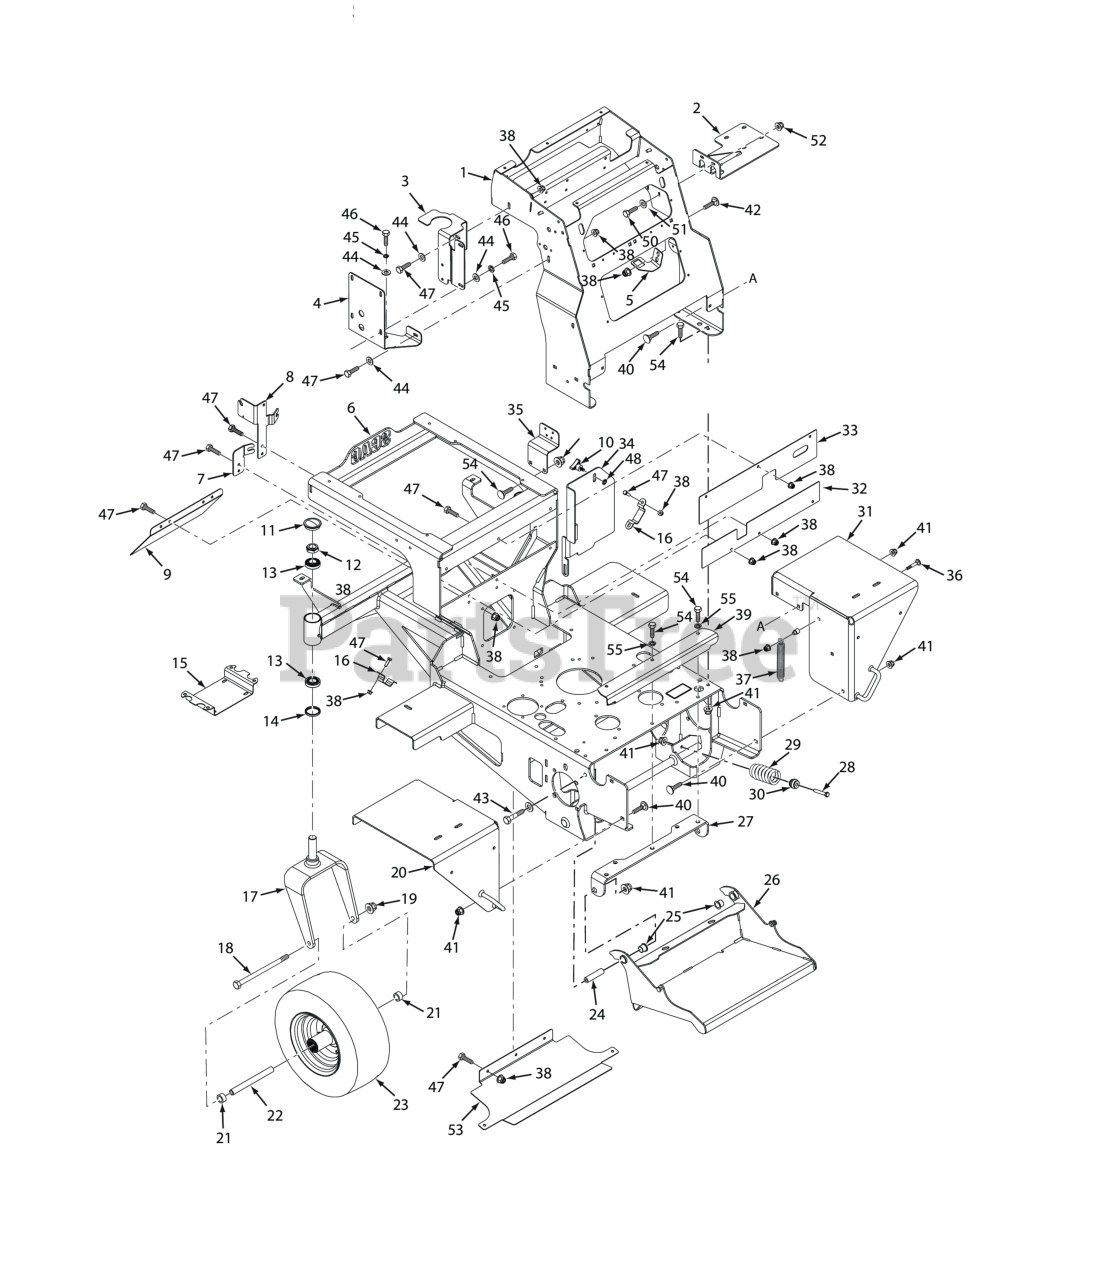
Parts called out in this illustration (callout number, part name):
1	Handlebar Weldment
2	Mounting Bracket, Hose Reel
3	Mounting Bracket, Oil Reservoir
4	Mounting Bracket, Fuel Tank
5	Mounting Bracket, Brake Switch
6	Mainframe Weldment, STS
7	Mounting Bracket, Door Cable
8	Mounting Bracket, Cable
9	Cover, Vent
10	Knob, w/ Stud, 5/16 - 18
11	Cap, Grease
12	Nut, Hex Elastic Stop 1.0"-14
13	Bearing Cone
14	Upright Post Weldment, RH
15	Mounting Bracket, Foamer Accessory (optional)
16	Bracket, Hose
17	Caster Yoke Weldment
18	Bolt, Hex Head 1/2-13 x 9-1/2" (61V & 72A/VS)
19	Nut, Elastic Stop 1/2-13, (STT-52 & STTII-52)
20	Fender, LH
21	Spacer, Caster Wheel
22	Sleeve, Caster Wheel (61V, 72A/VS)
23	Caster Wheel Assembly, 16 x 6.50 - 8
24	Spacer
25	Bearing, .750 I.D. Plastic
26	Footplate Assembly (Incl. #25)
27	Footplate Weldment
28	Bolt, Hex Head 3/8-16 x 2-1/4" - Stainless Steel
29	Spring, Suspension Platform
30	Mount, Spring
31	Fender, RH
32	Guard, Rear Hopper Lower
33	Guard, Rear Hopper Uppler
34	Battery Door
35	Mounting Bracket, Strainer
36	Bolt, Carriage 5/16-18 x 1.75 - Stainless Steel
37	Spring,Counter Balance
38	Locknut, 5/16-18 Flg. Elastic Stop - Stainless Steel
39	Mounting Bracket, Operator Presence
40	Bolt, Carriage 3/8-16 x 1.0 - Stainless Steel
41	Nut, Flange Elastic Stop 3/8 - 16 - Stainless Steel
42	Bolt, Carriage 5/16 - 18 x 1" - - Stainless Steel
43	Bolt, Hex 3/8 - 16 x 4.00 - Stainless Steel
44	Washer, Flat 5/16 -.375 x .875 x .0547/.104 - Stainless Steel
45	Washer, Lock 5/16 Spring - Stainless Steel
46	Bolt, Hex 5/16 - 18 x .75 - Stainless Steel
47	Bolt, Hex 5/16" - .375 x 1.00- Stainless Steel
48	Nut, Push On - Stainless Steel
49	Spring Bracke, Footplate
50	Bolt, Hex 1/4 - 20 x 1.00
51	Locknut, 1/4 - 20 Flg. Elastic Stop - Stainless Steel
52	Washer, Flat 1/4-.281X.625X.080 - Stainless Steel
53	Muffler Heat Shield
54	Bolt, Hex Head 3/8 - 16 x 1.50 - Stainless Steel
55	Lockwasher, 3/8-.377 x .680 x 094
